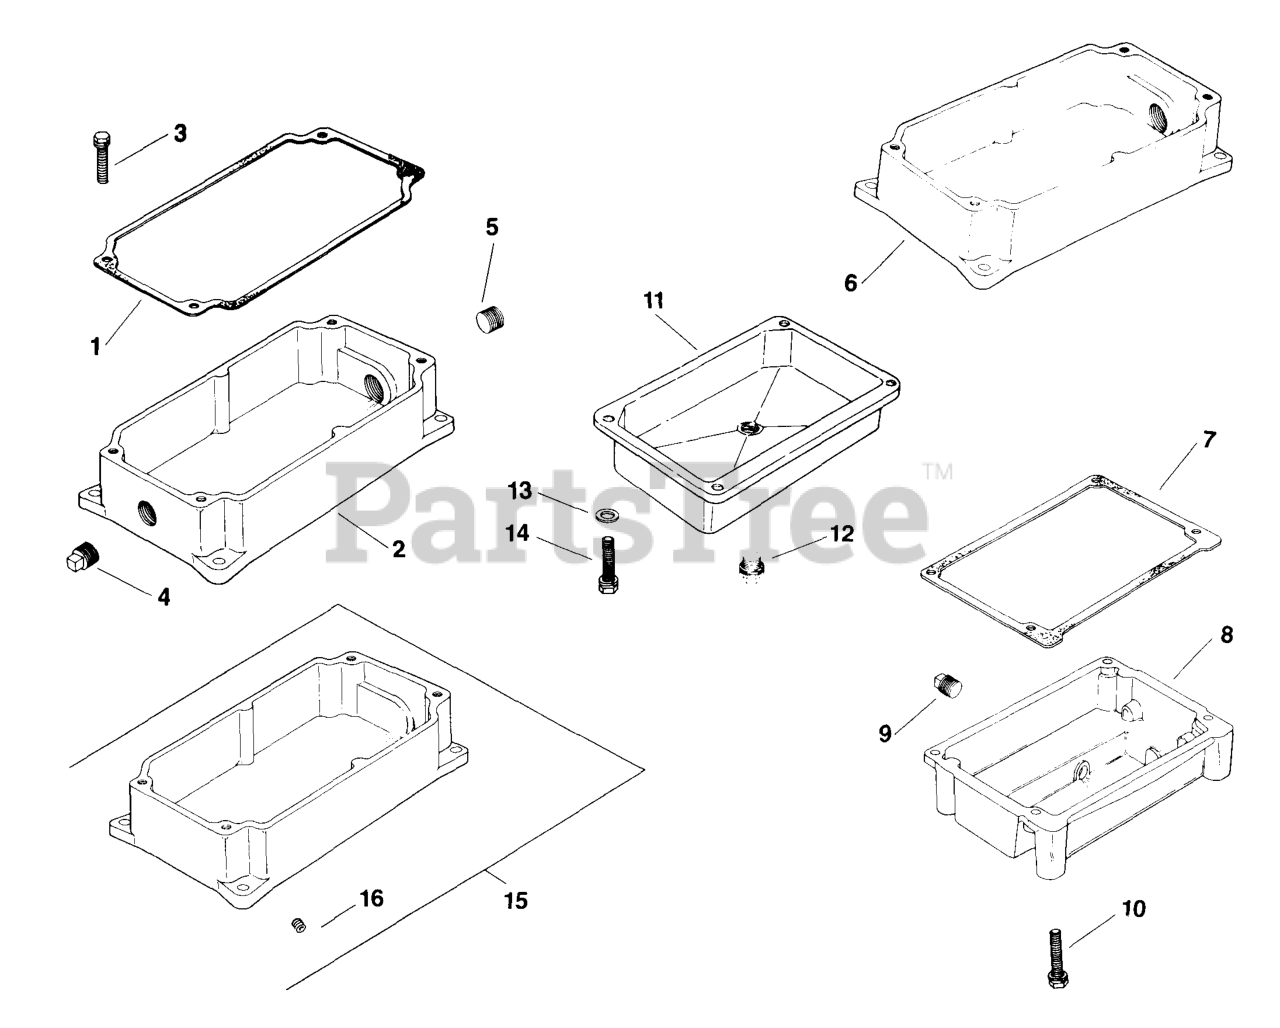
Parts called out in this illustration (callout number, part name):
1	GASKET, OIL PAN
2	PAN - DISCONTINUED
3	SCREW, SEMS 3/8-16X1-1/4" - DISCONTINUED
4	PLUG,PIPE SQ HD 3/4" USE 25 139 56-S
5	PLUG,PIPE 1/2 NPTF SQUARE HD USE 25 139 54-S
